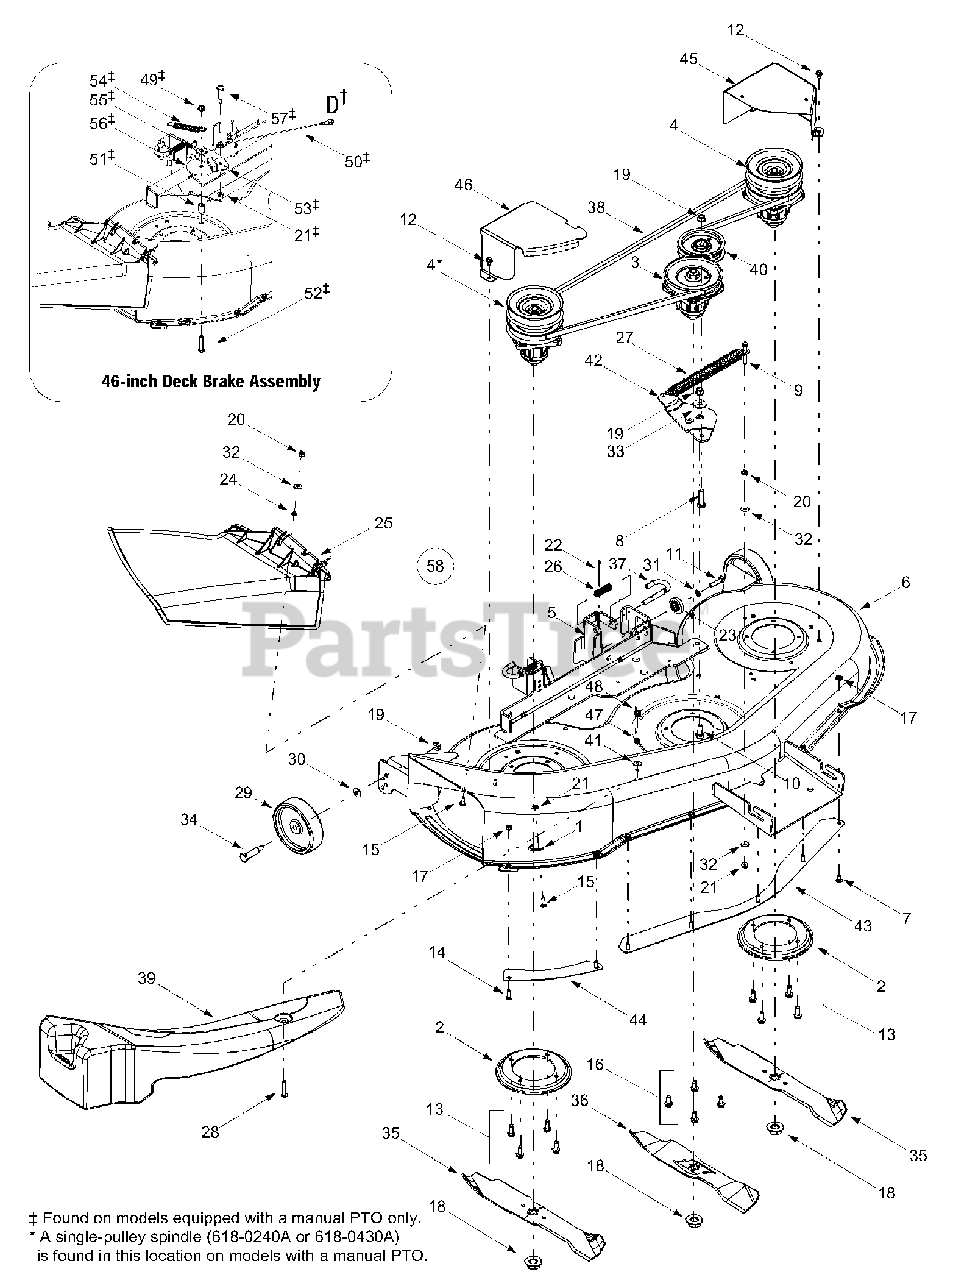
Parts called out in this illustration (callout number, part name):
1	Retainer Hook
4	Double Pulley Spindle Assembly
8	Hex Cap Screw, 3/8-16 x 1.5
9	Hex Cap Screw, 1/4-20 x 2.0
10	Hex Cap Screw, 3/8-16 x 1.0
11	Hex Cap Screw, 5/8-18 x 1.25
12	Self-tapping Screw,1/4-20 x .5
13	Self-tapping Screw,15/16-18 x .875
14	Hex Screw, 1/4-20 x .75
15	Hex Cap Screw, 1/4-20 x .62
16	Self-tapping Screw, 5/16-18 x .75
17	Hex Sems Nut, 1/4-20
18	Hex Flange Nut, 5/8-18
19	Flange Lock Nut, 3/8-16
20	Hex Nut, 1/4-20
21	Hex Flange Lock Nut, 1/4-20
22	Cotter Pin, 1/8 x 1.25
23	Deck Adjustment Gear
24	Push Nut. .25 x .5
25	Side Discharge Chute Assembly
26	Compression Spring, .406 x .531 x 1.75
27	Extension Spring, .91 x 7.3
28	Screw, 1/4-20 x 1.5
29	Deck Wheel, 5 x 1.38
30	Bell Washer, .401 x .87 x .063
31	Lock Washer, 5/16
32	Bell Washer, .265 x .75 x .062
33	Shoulder Spacer, .625 x 1.16
34	Shoulder Screw
35	Three-in-one Blade, Star Center, 16.28"
36	Three-in-one Blade, Star Center, 14.88"
37	Deck Release Pin
38	Deck Belt, Poly
39	Mulch Plug
40	Idler Pulley, 3.5
41	Flat Washer, .28 x .74 x .063
48	Wing Nut, 1/4-20
49	Hex Nut, 5/16-18
50	Bracket Cable, 12"
51	Spacer, .385 x .625 x .70
52	Hex Cap Screw, 5/16-18 x 1.5
53	Deck Brake Assembly
54	Extension Spring, .5 x 3.97
55	Shoulder Spacer
56	Flat Washer, .320 x 3.0 x .125
57	Shoulder Screw, .374 x 1.16
